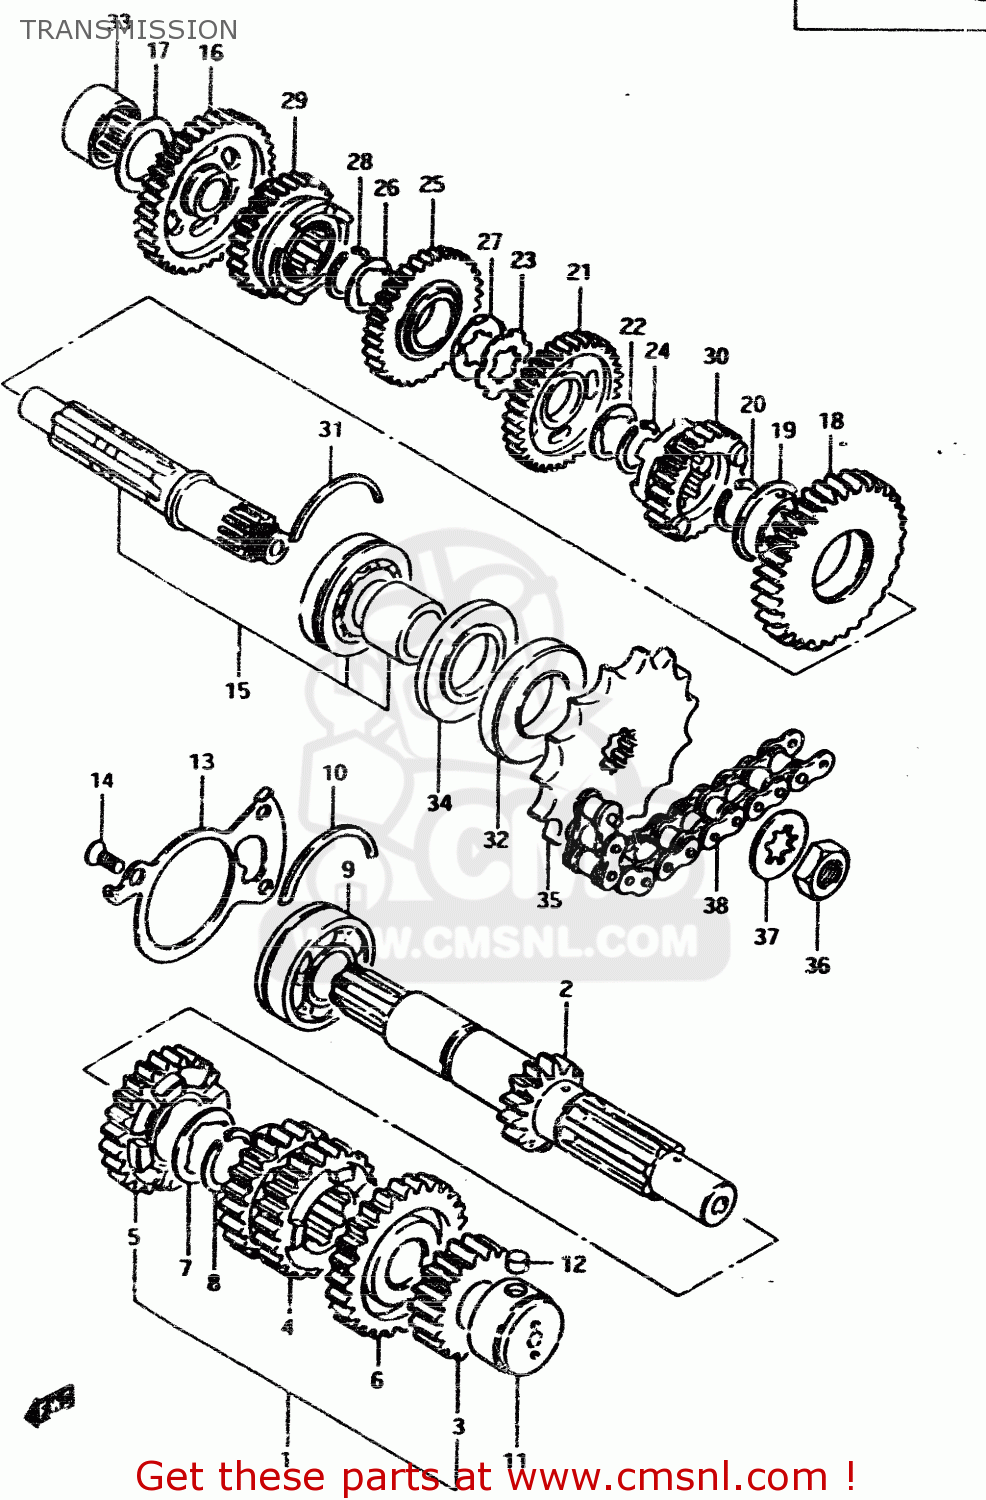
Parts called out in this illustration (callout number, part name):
1	SHAFT,COUNTER
2	SHAFT,COUNTER
3	GEAR,2ND DRIVE(NT:18)
4	GEAR,THIRD DRIVE
5	GEAR,FIFTH DRIVE
6	GEAR,SIXTH DRIVE
7	WASHER
8	CIRCLIP
9	BEARING(25X62X17)
10	C-RING
11	ROLLER BEARING (20X34X2
12	PIN
13	PLATE,COUNTERSHAFT BEARING
14	SCREW
15	SHAFT,DRIVE
16	GEAR,FIRST DRIVEN
17	WASHER
18	GEAR,SECOND DRIVEN
19	BUSHING
20	CIRCLIP
21	GEAR,THIRD DRIVEN
22	WASHER,LOCK
23	WASHER,LOCK
24	CIRCLIP
25	GEAR,FOURTH DRIVEN
26	WASHER,LOCK
27	WASHER
28	CIRCLIP
29	GEAR,5TH DRIVEN(NT:25)
30	GEAR,SIXTH DRIVEN
31	C-RING
32	SEAL,OIL(32X62X7)
33	ROLLER BEARING (20X34X1
34	SEAL,OIL(32X62X5.5)
35	SPROCKET,ENGINE(NT:16)
36	NUT
37	WASHER
38	CHAIN,DRIVE #50UB-108
